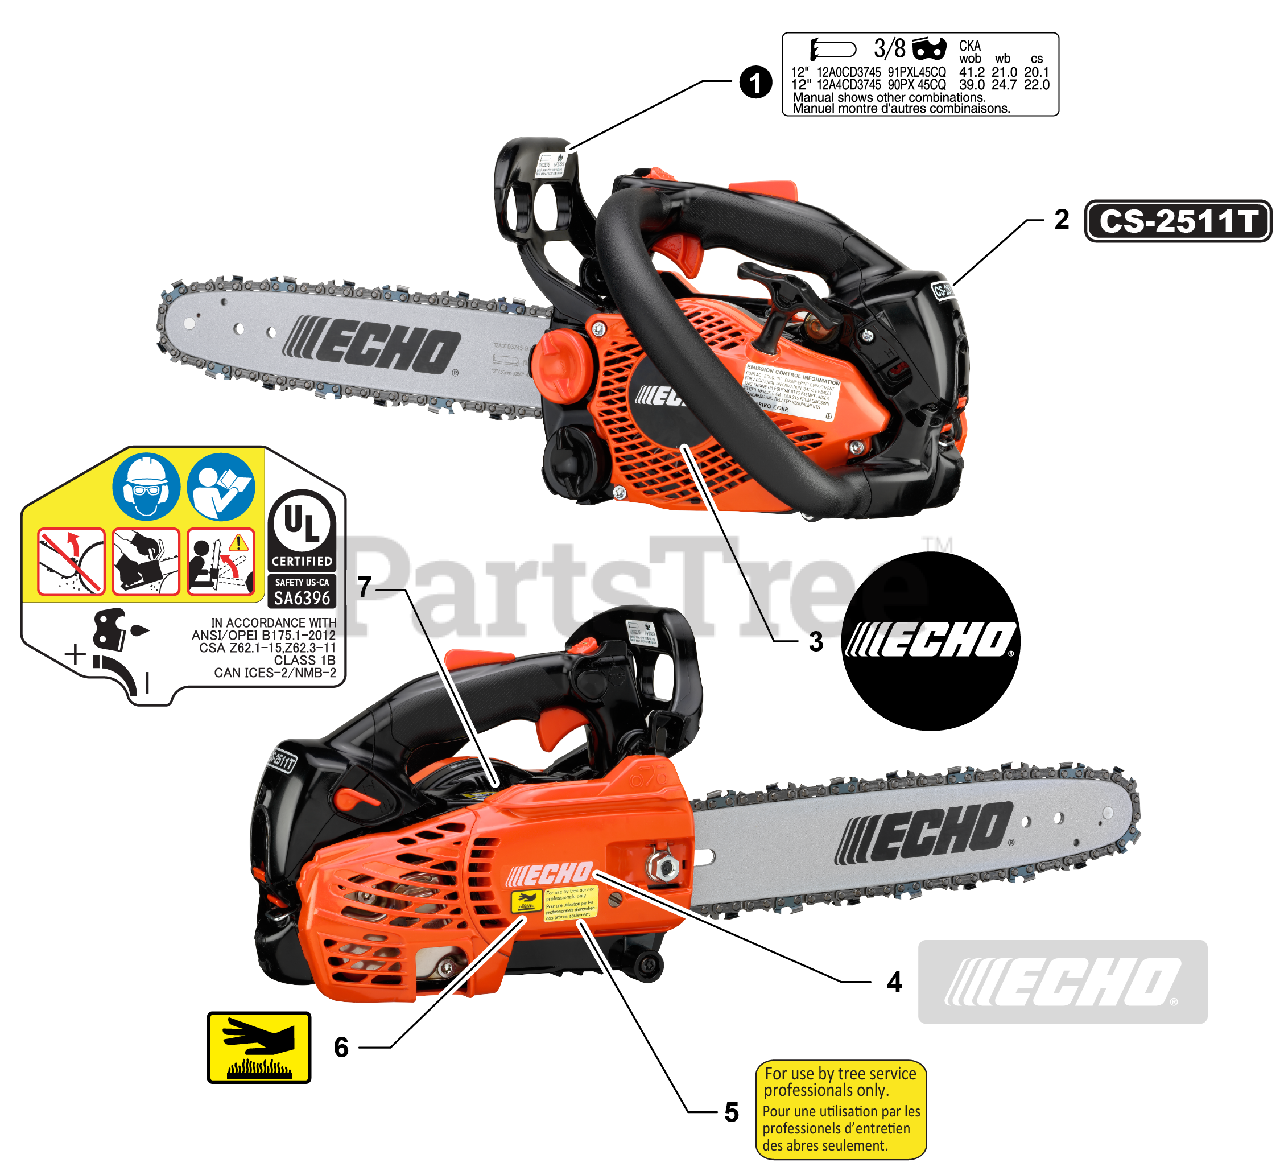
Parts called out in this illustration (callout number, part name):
1	LABEL, BAR & CHAIN
2	LABEL, CS-2511T
3	LABEL, ECHO
4	LABEL, ECHO
5	LABEL, CAUTION - PROFESSIONALS ONLY
6	LABEL, CAUTION - HOT
7	LABEL, CAUTION
